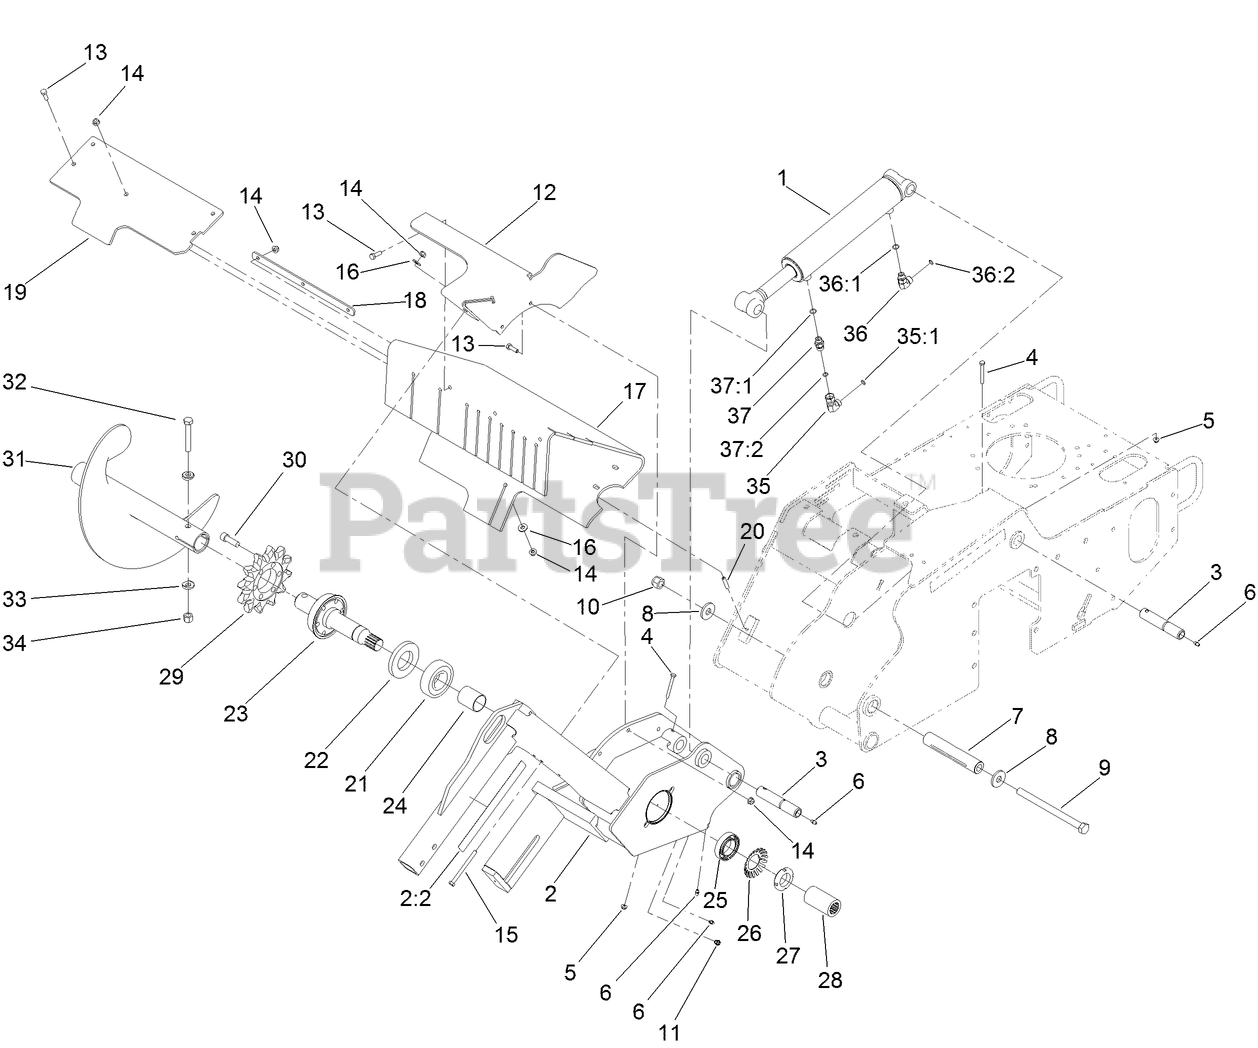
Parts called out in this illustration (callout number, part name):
1	HYDRAULIC CYLINDER ASM
2	TRENCHER HEAD ASM
2:2	DECAL-DANGER
3	PIN-PIVOT
4	SCREW-HH
5	NUT-HF
6	FITTING-GREASE
7	SPACER-PIVOT
8	WASHER-HARDENED
9	BOLT-HH
10	NUT-LOCK, NI
11	FITTING-LUBE
12	BRACKET-SHIELD
13	SCREW-HH
14	NUT-HF, NI
15	SCREW-HH
16	WASHER-FLAT
17	SHIELD-DIRT
18	PLATE-STRAP, SHIELD
19	BAR-CLAMP
20	SCREW-HSH
21	BEARING-BALL
22	SEAL-GREASE
23	SHAFT-TRENCHER
24	SPACER
25	BEARING-BALL
26	LOCKWASHER-BEARING
27	LOCKNUT-BEARING
28	COLLAR-SPLINED
29	SPROCKET-TRENCHER
30	SCREW-HSH
31	AUGER-TRENCHER
32	SCREW-HH
33	WASHER-SADDLE
34	NUT-LOCK, NI
35	FITTING-HYD, 90 DEG
35:1	O-RING
36	FITTING-ELBOW, 90 DEG
36:1	O-RING
36:2	O-RING
37	VALVE-CHECK
37:1	O-RING
37:2	O-RING
